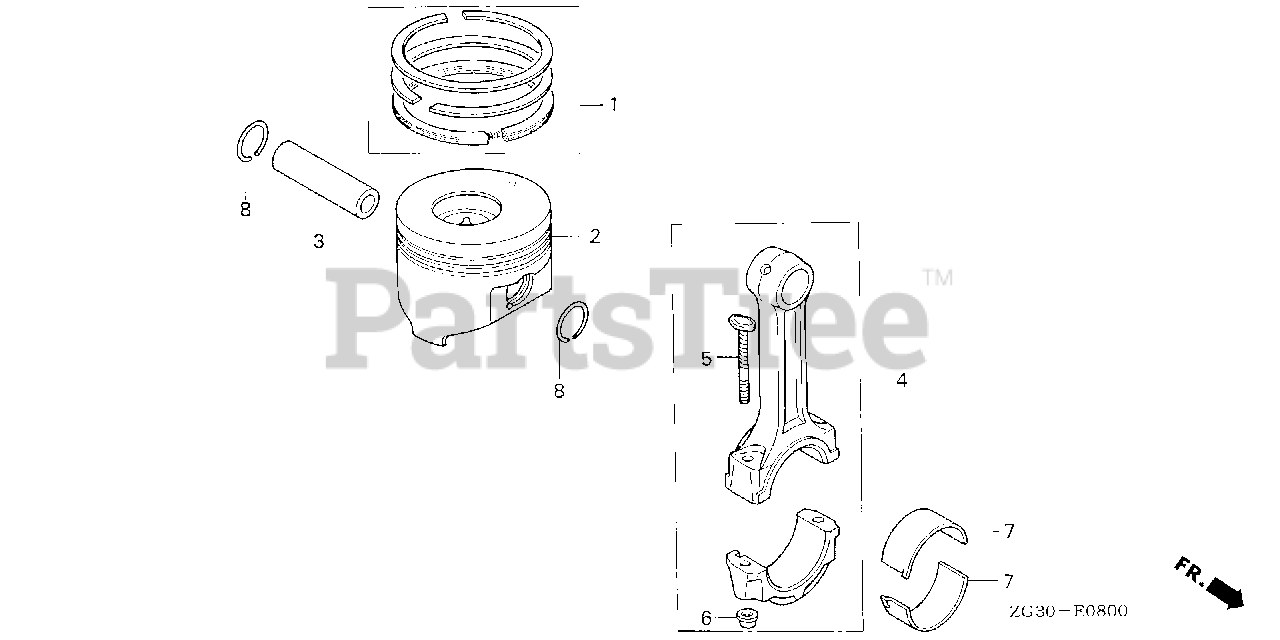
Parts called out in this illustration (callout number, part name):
1	RING SET, PISTON (STD)
1	RING SET, PISTON (0.25)
1	RING SET, PISTON (0.50)
1	RING SET, PISTON (0.75)
2	PISTON (STD)
2	PISTON (0.25)
2	PISTON (0.50)
2	PISTON (0.75)
3	PIN, PISTON
4	ROD ASSY., CONNECTING
5	BOLT, CONNECTING ROD (8X51)
6	NUT, CONNECTING ROD
7	BEARING A, CONNECTING ROD (BLUE)
7	BEARING B, CONNECTING ROD (BLACK)
7	BEARING C, CONNECTING ROD (BROWN)
7	BEARING D, CONNECTING ROD (GREEN)
7	BEARING E, CONNECTING ROD (YELLOW)
7	BEARING, CONNECTING ROD (F)(PINK)
7	BEARING G, CONNECTING ROD (RED)
7	BEARING A, CONNECTING ROD (UNDER SIZE 0.25) (BLACK)
7	BEARING B, CONNECTING ROD (UNDER SIZE 0.25) (BROWN)
7	BEARING C, CONNECTING ROD (UNDER SIZE 0.25) (GREEN)
7	BEARING A, CONNECTING ROD (UNDER SIZE 0.50) (BLACK)
7	BEARING B, CONNECTING ROD (UNDER SIZE 0.50) (BROWN)
7	BEARING C, CONNECTING ROD (UNDER SIZE 0.50) (GREEN)
7	BEARING A, CONNECTING ROD (UNDER SIZE 0.75) (BLACK)
7	BEARING B, CONNECTING ROD (UNDER SIZE 0.75) (BROWN)
7	BEARING C, CONNECTING ROD (UNDER SIZE 0.75) (GREEN)
8	CLIP, PISTON PIN
